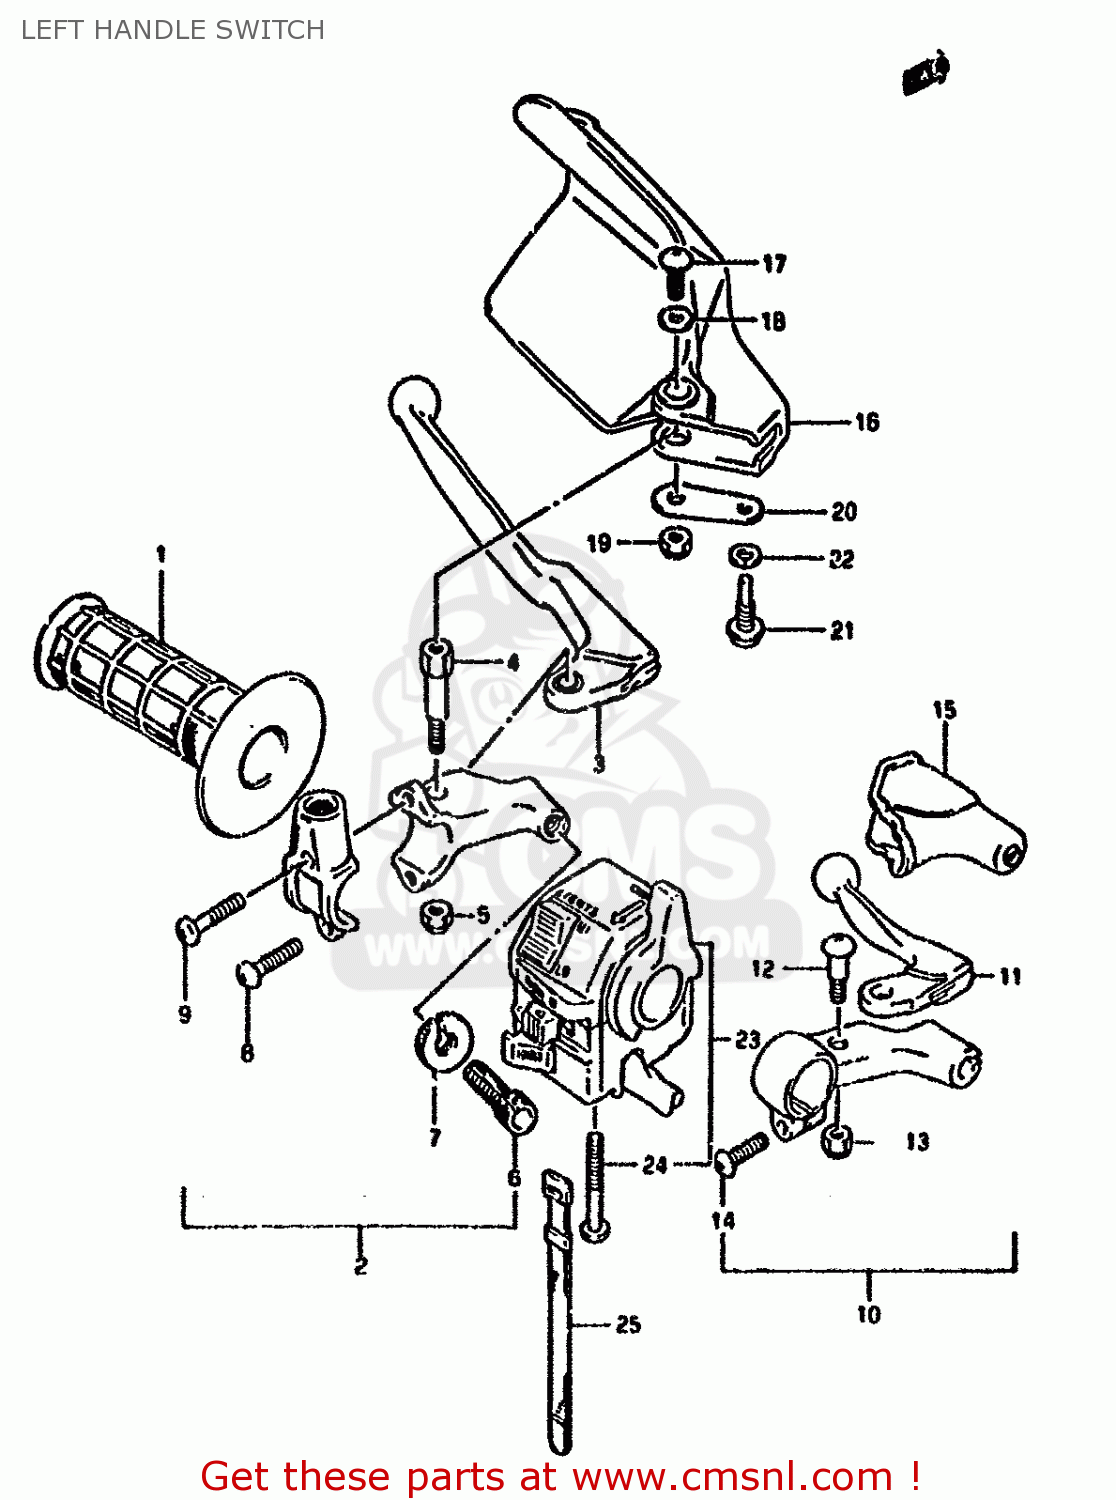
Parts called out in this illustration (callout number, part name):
1	GRIP,L
2	LEVER ASSY,CLUTCH
3	LEVER,CLUTCH
4	BOLT,LEVER SET
5	NUT 6MM
6	ADJUSTER,CABLE
7	NUT,LOCK
8	SCREW
9	SCREW(5X22)
10	LEVER ASSEMBLY,DECOMPRESSION
11	LEVER,DECOMP
12	BOLT,LEVER PIVOT
13	NUT
14	SCREW
15	COVER,DECOMP LEVER DUST
16	COVER,KNUCKLE,L
17	SCREW
18	WASHER (5.5X16X1.2)
19	NUT 6MM
20	PLATE,KNUCKLE COVER,L LWR
21	SCREW
22	WASHER,LOCK
23	SWITCH,HANDLE,
24	SCREW, 5X45
25	CLAMP(L:120)
